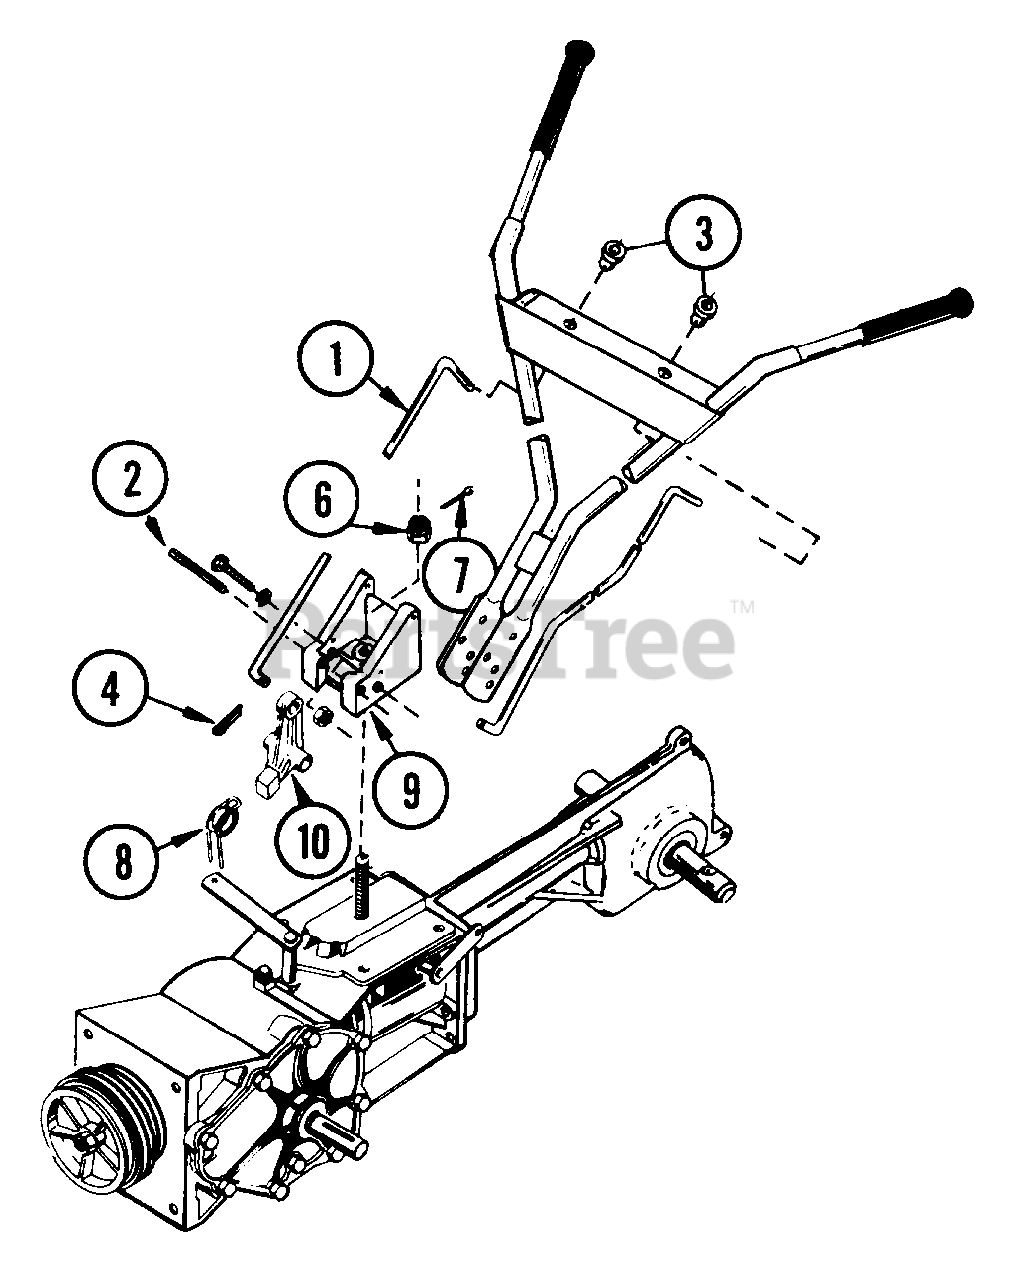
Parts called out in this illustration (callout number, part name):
1	POSITION ROD
2	PIN-ROLL .313X2.00
3	SNAP BUSHING
4	PIN-COTR .09X.75 PL
6	NUT-SL .50-13
7	PIN-COTR .12X1.0 PL
8	SG-TORS .109X.88X2.25
9	HANDLEBAR BRACKET
